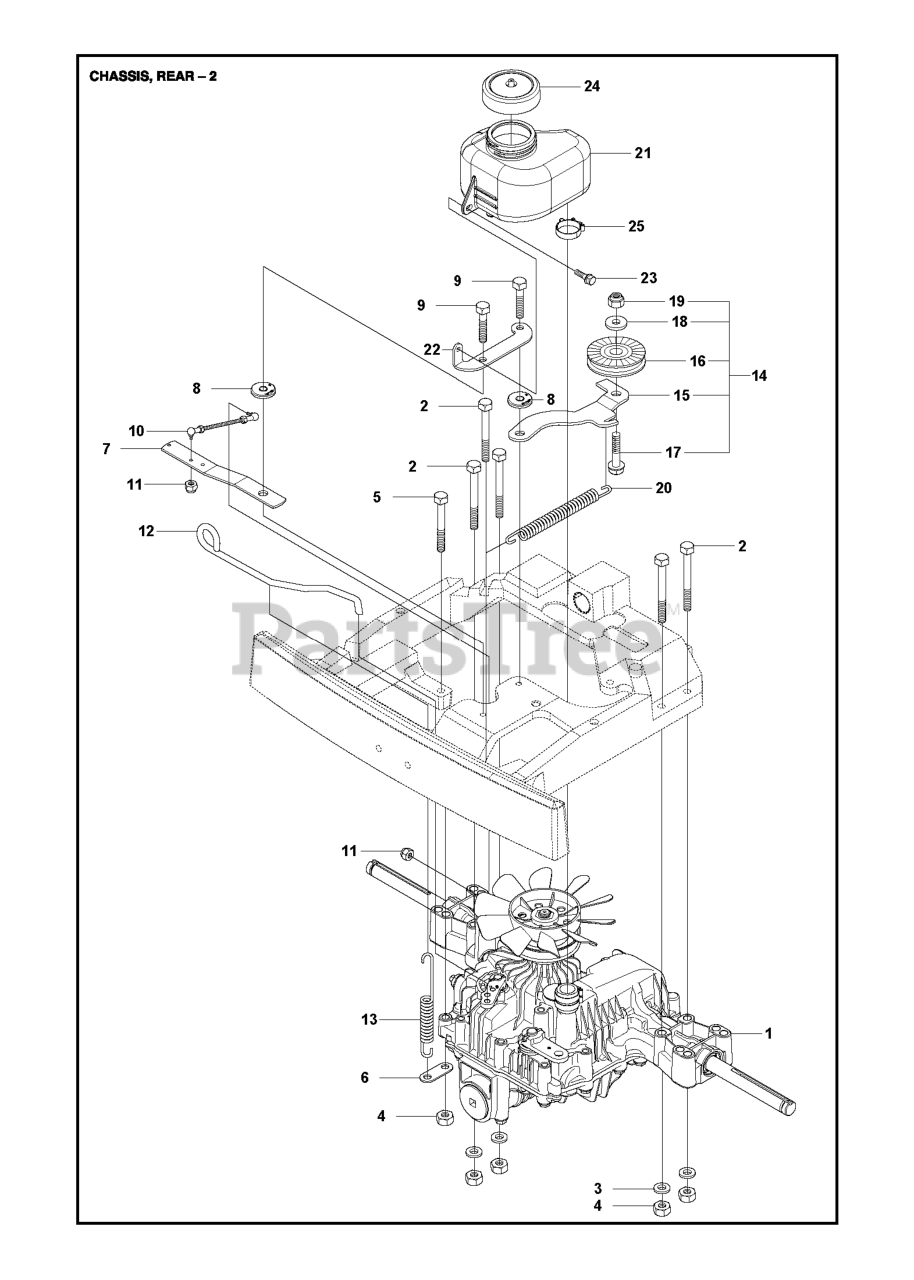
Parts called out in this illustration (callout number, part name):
1	TRANSMISSION K574A
3	WASHER BRB 8.4X17
4	NUT
11	LOCKNUT M5
15	BELT TENSIONER ARM
19	LOCKNUT M8
20	SPRING
21	TANK
21	EXPANSION TANK RIDER EXTENDED
25	HOSE CLAMP 20-32
